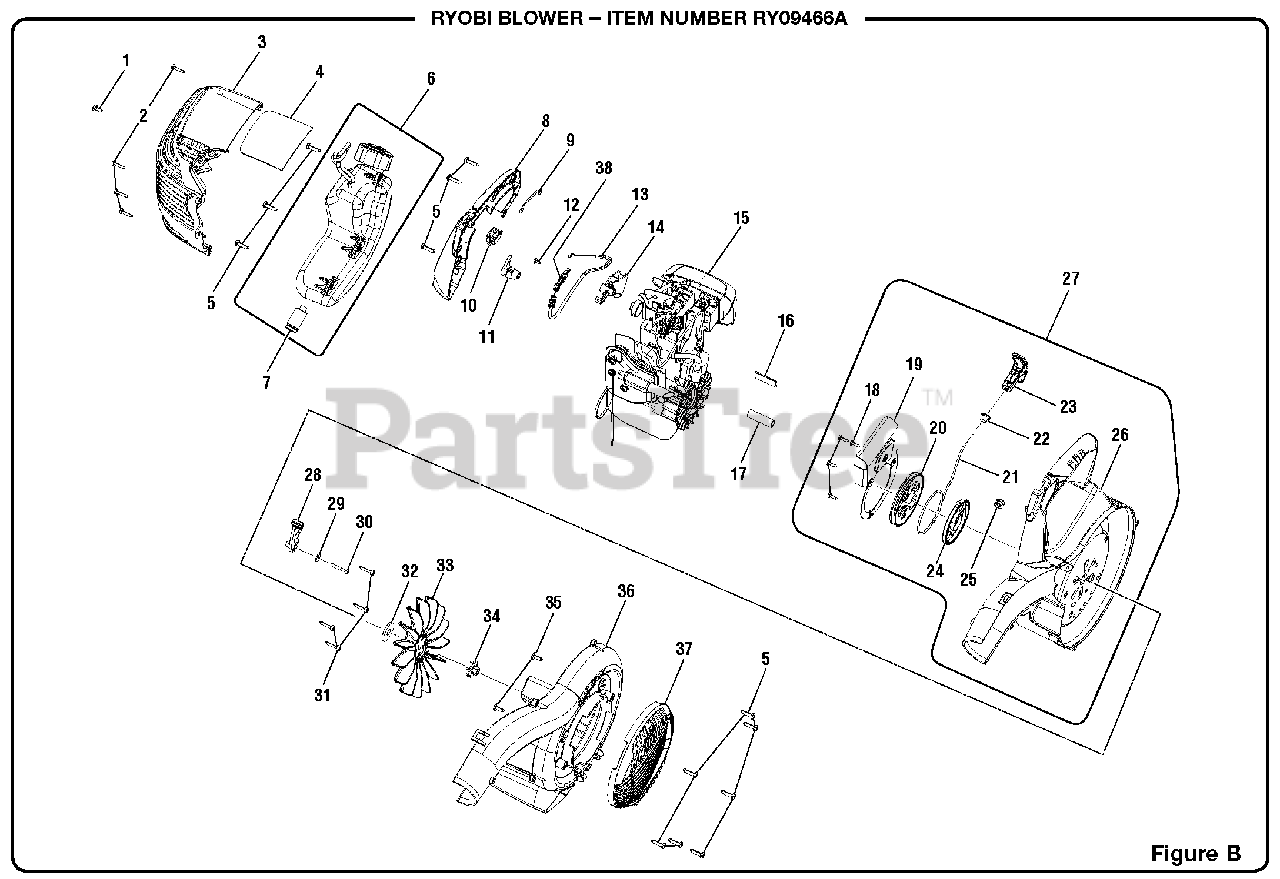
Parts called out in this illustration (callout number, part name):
1	Screw (M5 x 10.5 mm, T20 Torx Hd. )
2	Screw (M4 x 18 mm, T20 Torx Soc. Hd.)
3	Engine Housing
4	Heat Shield
5	Screw (#10-14 x 3/4 in, T25 Torx Pan Hd. T.F.)
6	Fuel Tank Assembly w/Cap
7	Fuel Filter
8	Handle Cover
9	Ground Wire
11	Trigger Lock
12	Screw (M3.5 x 7.5 mm, T20 Torx Pan Hd.)
13	Throttle Cable
15	Power Head Assembly
18	Screw (M4 x 12 mm, T20 Torx Truss Hd.)
20	Starter Pulley
21	Starter Rope
23	Starter Grip
24	Container Spring Assembly
26	Inner Volute
27	Lower Housing w/Starter
28	Cruise Lever
29	Washer (ID4.3 x OD12 x 1.5t)
30	Cruise Lever Screw (M8-14 x 25 mm, Special T20 Truss Hd.)
31	Screw (M4 x 23 mm, T20 Truss Hd. T.F.)
32	Washer (ID9.8 x OD34.27 x 2.28t)
34	Blower Fan Nut (3/8-24)
35	Screw (#10-14 x 1/2 in., T25 Torx Truss Hd.)
36	Outer Volute
37	Air Inlet Cover
38	Throttle Lever
